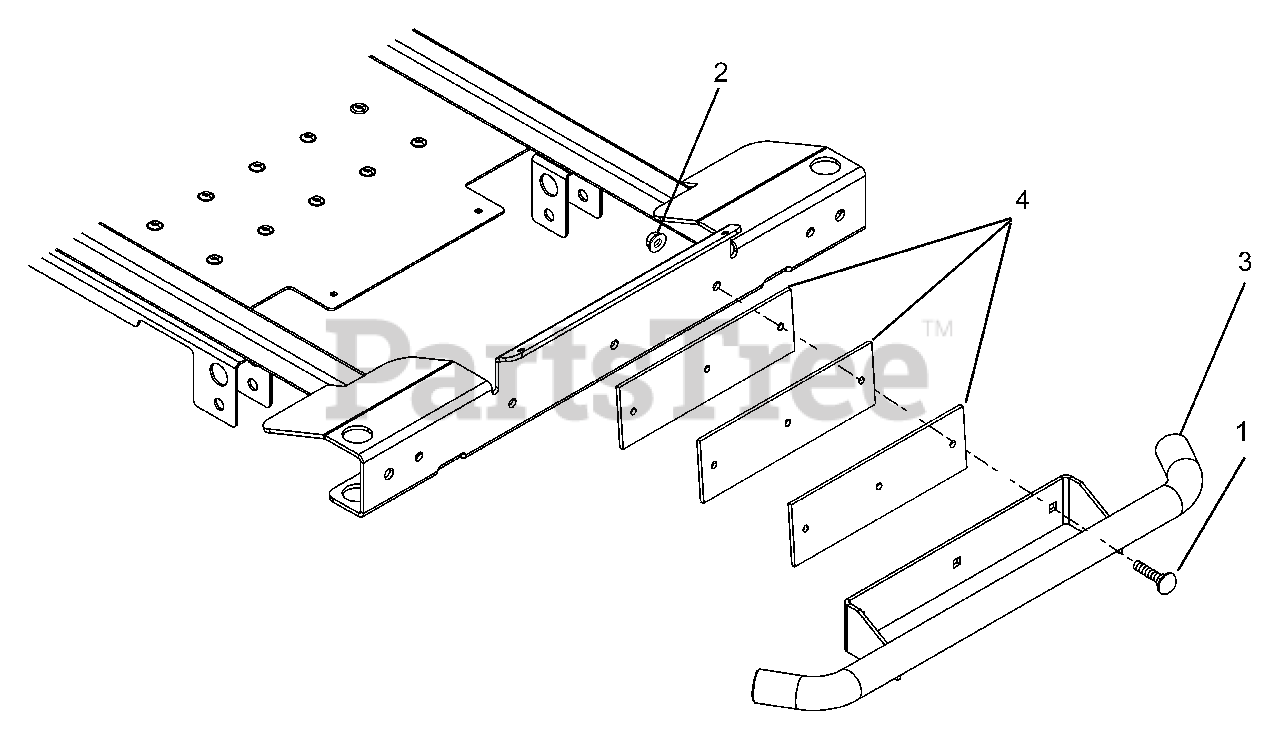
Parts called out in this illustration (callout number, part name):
1	@BLT-RDHDSQNK .38-16X2.00 G5YZ
2	@NUT-LK-NYL-FLG .38-16 YWZC
4	PLATE,COUNTERWEIGHT
